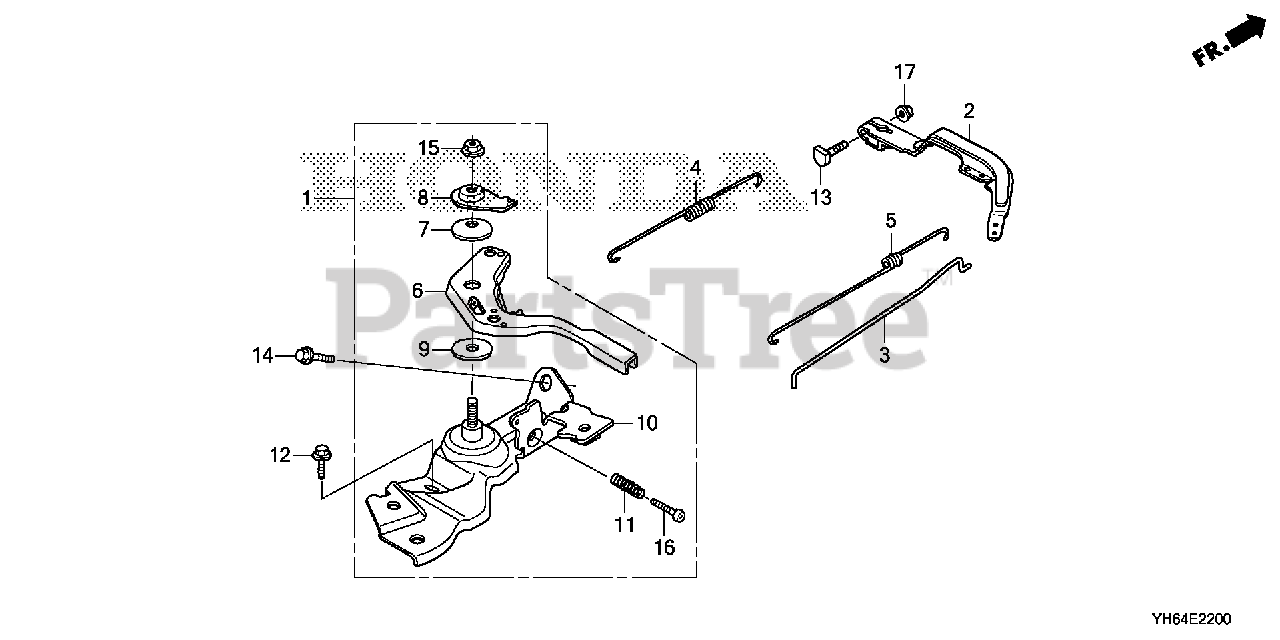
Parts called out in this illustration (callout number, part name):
1	CONTROL ASSY.
2	ARM, GOVERNOR
3	ROD, GOVERNOR
4	SPRING, GOVERNOR
5	SPRING, THROTTLE RETURN
6	LEVER, CONTROL
7	SPRING, LEVER
8	WASHER, CONTROL LEVER
9	SPACER, CONTROL LEVER
10	BASE, CONTROL
11	SPRING, CONTROL ADJUSTING Use from Engine SN 2327377.
12	BOLT, FLANGE (6X12) (CT200)
13	BOLT, GOVERNOR ARM
14	BOLT, FLANGE (6X20) (CT200)
15	NUT, SELF-LOCK (6MM)
16	SCREW, PAN (5X25)
17	NUT, FLANGE (6MM)
